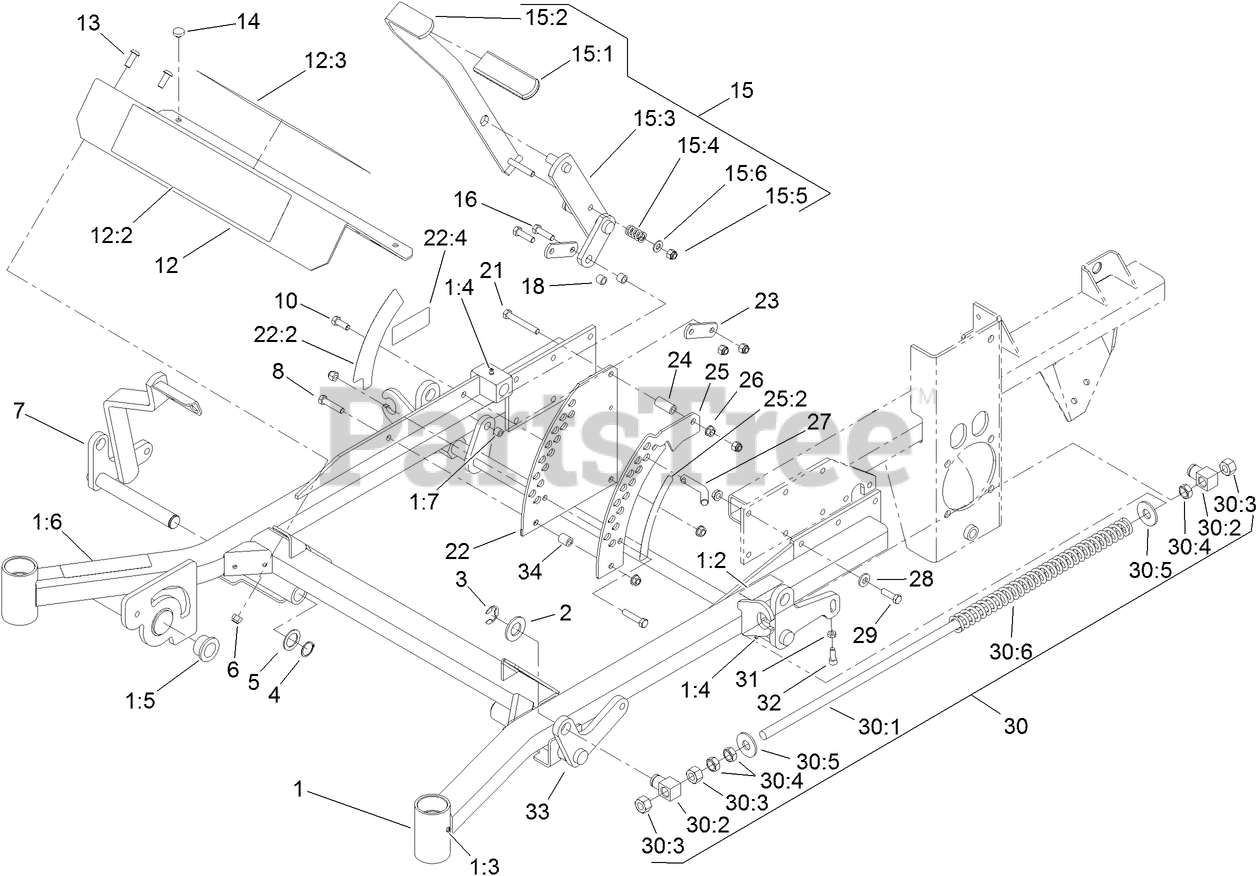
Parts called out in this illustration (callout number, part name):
1	Frame ASM
1:2	Decal-Brake, Parking
1:4	FITTING-GREASE
1:5	BUSHING
1:6	DECAL-WARNING
1:7	Bushing
2	WASHER-FLAT
3	RING-RETAINING, EXT
4	RING-RETAINING
5	WASHER-SPACER
6	NUT-LOCK, NI
7	LIFT-DECK, RH FRONT
8	SCREW-HH
10	SCREW-HH
12	FOOTREST
12:3	DECAL-WARNING
13	SCREW-HSBH
14	BUMPER
15	DECK LIFT HANDLE ASM
15:1	GRIP-LEVER, LIFT
15:2	LEVER-LIFT
15:3	ARM-LIFT, DECK
15:4	SPRING-COMPRESSION
15:5	NUT-LOCK, NI
15:6	WASHER-FLAT
16	SCREW-HH
18	Bushing
21	SCREW-HH
22	PLATE-HOC, OUTER
22:2	Decal-Height, Deck
22:4	DECAL-ARRESTER, SPARK
23	ARM-LIFT, DECK
24	BUSHING-LEVER, LIFT
25	PLATE-HOC, INNER
25:2	Decal-Height, Deck
26	NUT-HHF, WHIZ
27	PIN-HOC
28	WASHER-BELLEVILLE
29	SCREW-HH
30	FRONT FRAME SPRING ASM
30:1	ROD-LIFT, DECK
30:2	SWIVEL-DECK MOUNT, REAR
30:3	NUT-HEX
30:4	NUT-JAM
30:5	WASHER-FLAT
30:6	SPRING-SUPPORT, DECK
31	NUT-JAM
32	SCREW-HSH
33	LIFT-DECK, LH
34	BUSHING-LEVER, LIFT
